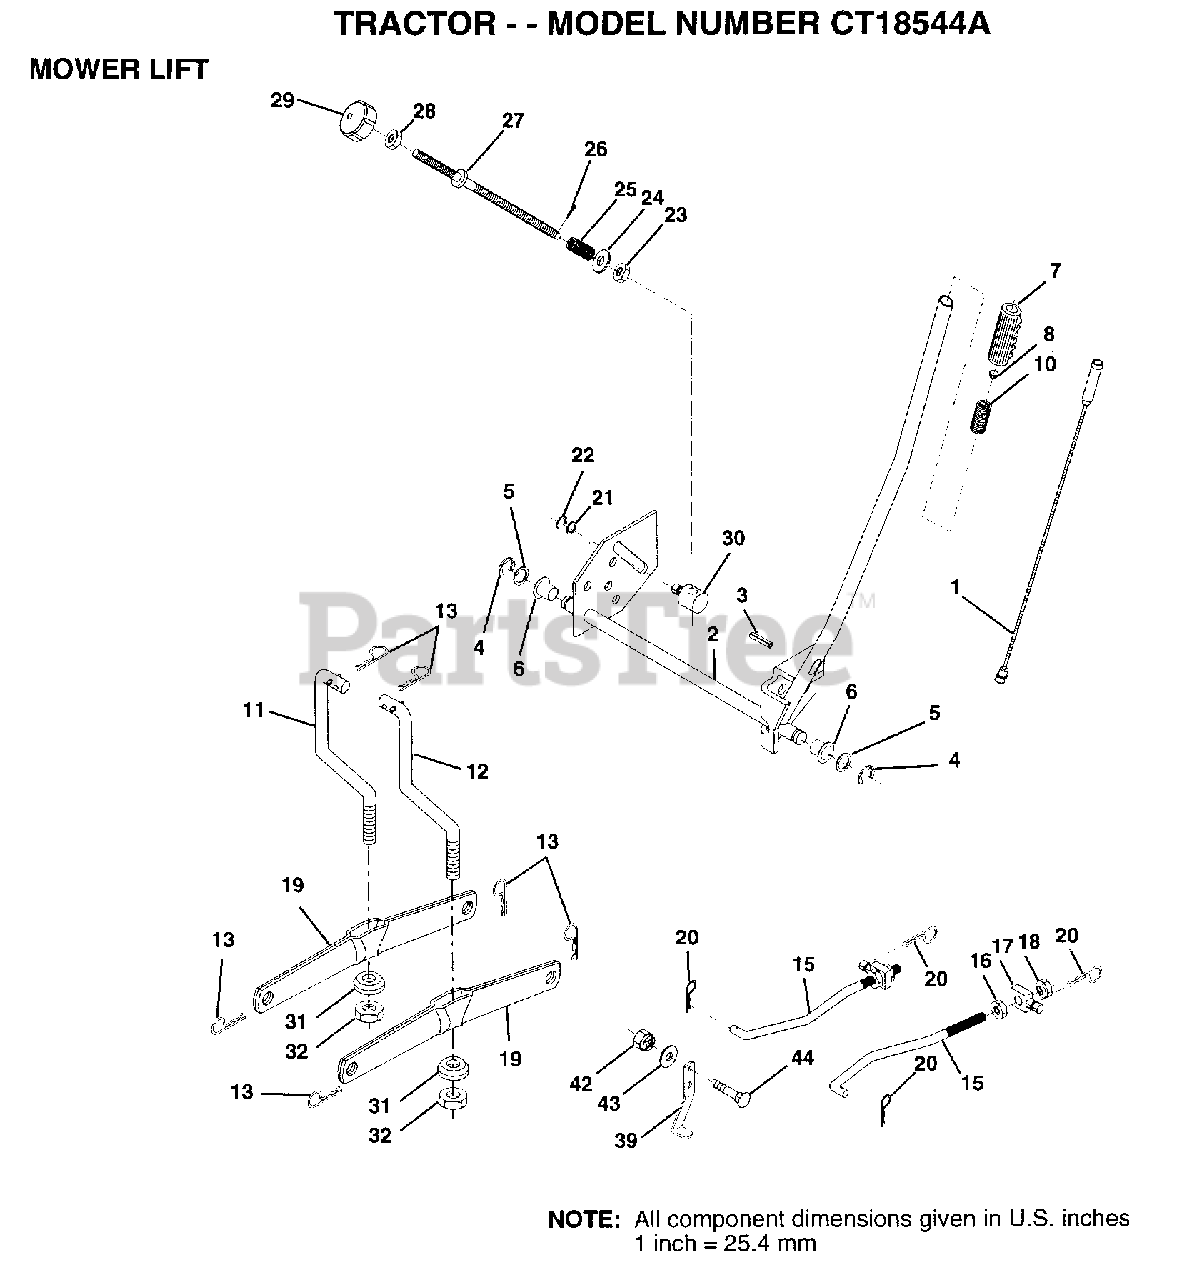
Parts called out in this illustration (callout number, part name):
1	LEVER ROD LT
2	SHAFT LIFT W/IND
6	"BOLT,HEX"
7	GRIP
10	SPRING T
11	LINK.LIFT.LH.GTV
12	LINK.LIFT.RH.GTV.
15	LINK.FRONT
16	NUT
17	TRUNION
18	NUT.LK.W/WSH.1/2.
19	ARM SUSP REAR
20	RETAINER.SPRING
21	WASHER
22	KLIP RING
23	NUT T
24	WASHER
25	SPRING.COMP.INF.H
27	ROD.ADJ.LIFT
28	NUT
29	KNOB INF 3/8-16
30	TRUNION LT
31	BEARING PVT LH
32	NUT.CROWNLOCK.3/8
39	STOP.OVER.CENTER
43	WASHER GT
44	BOLT
46	E-RING
47	WASHER
